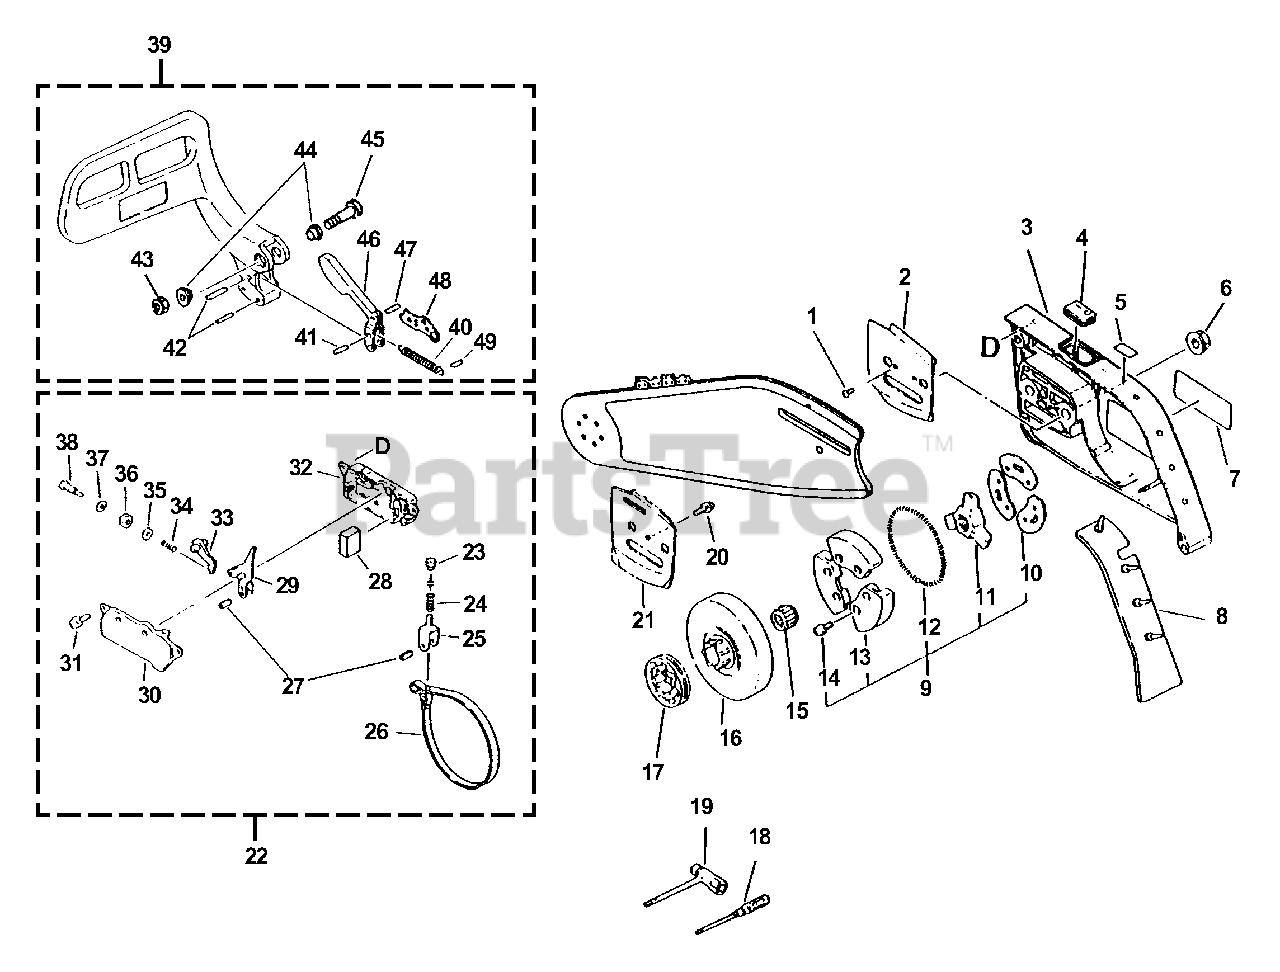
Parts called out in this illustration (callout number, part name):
1	SCREW - 3X6
2	PLATE, GUIDE - OUTER
3	GUARD, SPROCKET
5	LABEL - CAUTION
6	NUT - FLANGE
7	LABEL - ECHO
9	CLUTCH ASSY
10	PLATE, CLUTCH
11	HUB, CLUTCH
12	SPRING, CLUTCH
13	CLUTCH SHOE SET
14	SCREW - 4X6
15	BEARING, NEEDLE
16	DRUM, CLUTCH
17	SPROCKET, RIM
18	SCREWDRIVER
19	T-WRENCH - 13X19mm
20	SCREW - 4X8
21	PLATE, GUIDE - INNER
22	CHAIN BRAKE ASSY
25	ADJUSTER, BRAKE BAND
26	BAND, BRAKE
27	PIN - SPRING -- 4X10
29	LEVER, BRAKE
30	COVER, BRAKE
31	SCREW - 4X10
32	COVER, BRAKE
33	STOPPER, BRAKE
34	SPRING, BRAKE
37	WASHER - 5
39	BRAKE LEVER ASSY
40	SPRING, RETURN
41	PIN - SPRING -- 3X12
42	PIN - 3X24
43	LOCKNUT - 5
45	SCREW - 5X30
46	WEIGHT, BRAKE
47	PIN - SPRING -- 4X8
48	STOPPER
49	PIN - SPRING -- 3X16
